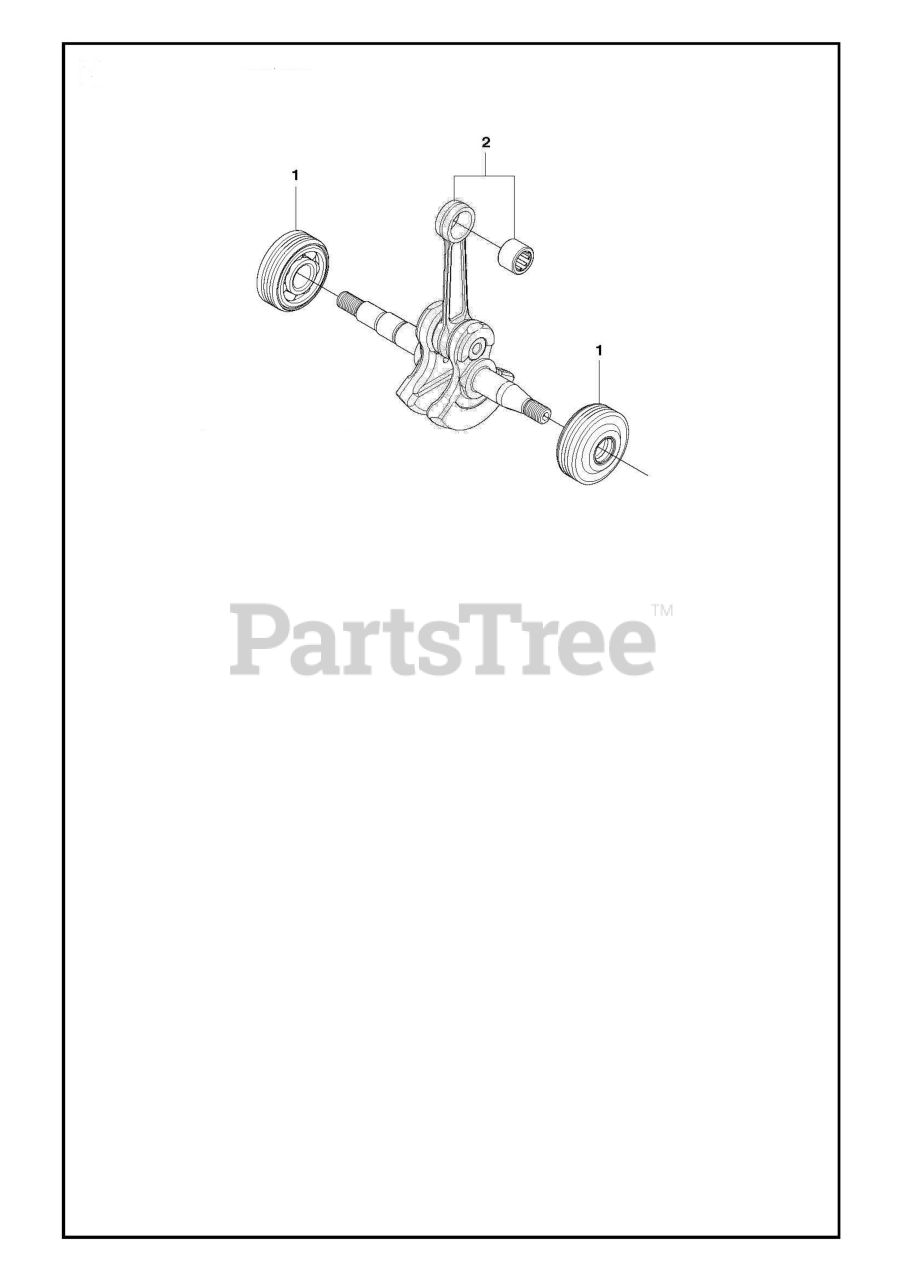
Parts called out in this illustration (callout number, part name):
1	BEARING & SEAL ASSEMBLY
1	ASSY SEAL & BEARING
2	ASSY CRANKSHAFT
